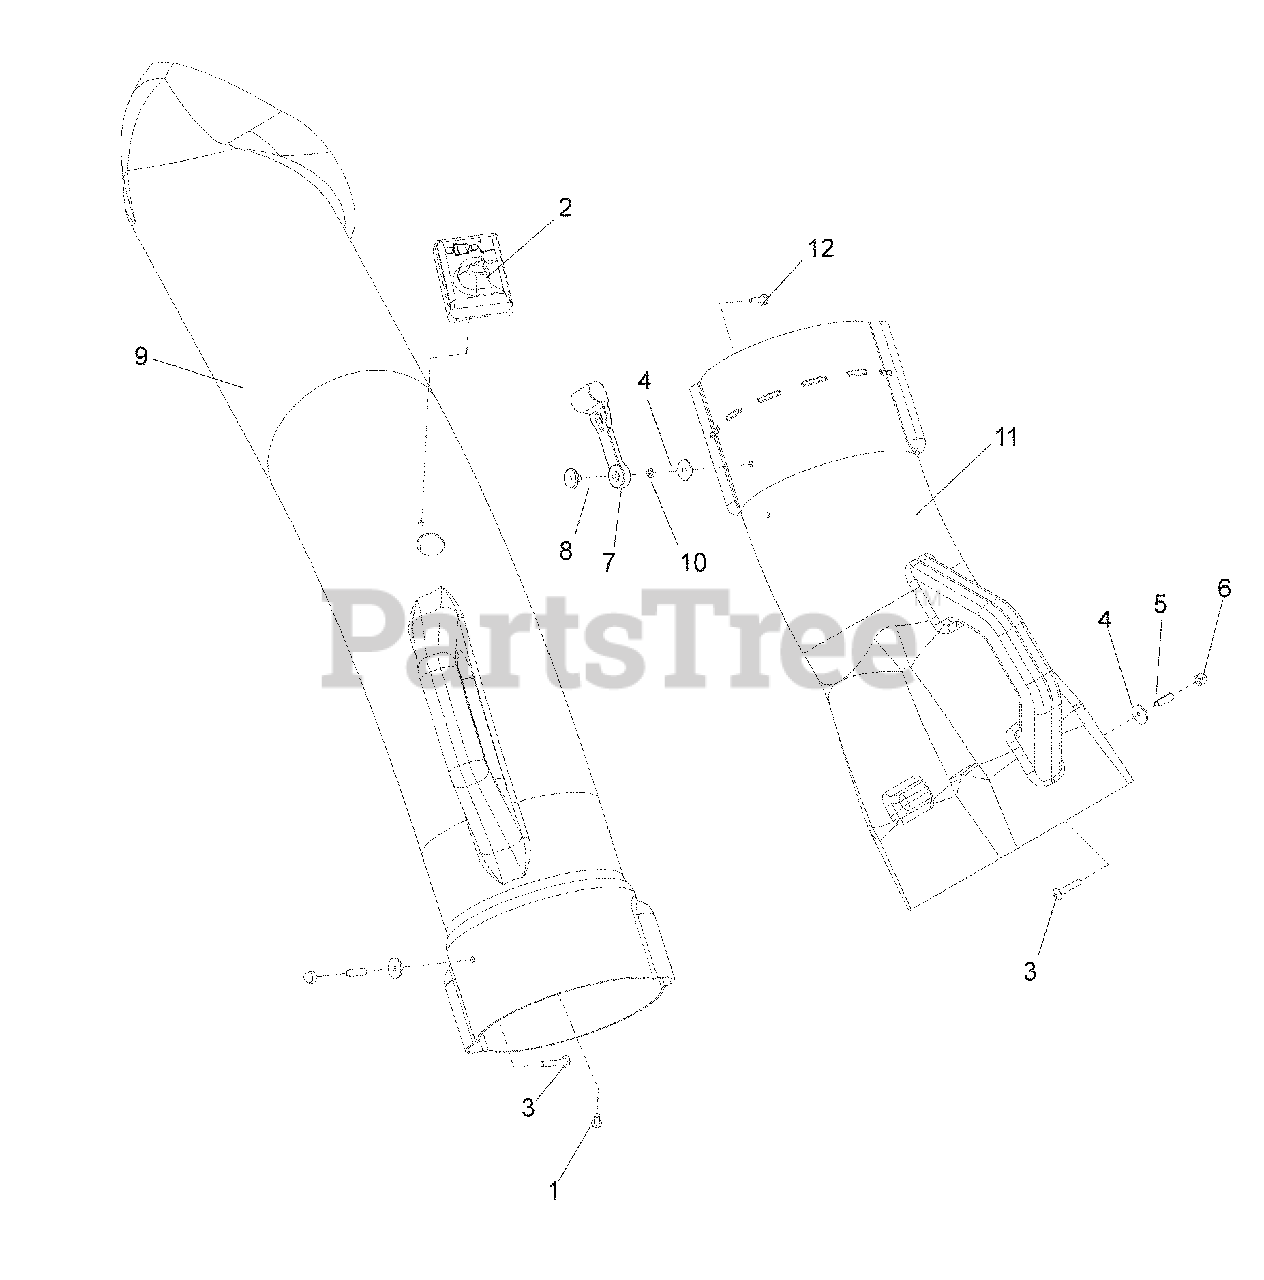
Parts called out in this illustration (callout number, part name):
1	SCREW, SPEC 10-14 x ½
2	INDICATOR, BAG DUMP
3	SCREW 10-24 x 11/8
4	WASHER 3/16 x ¾ x 16 GA
5	SPACER, SPLIT
6	NUT, ACORN 10-24
7	LATCH, HOOD
8	WELD NUT, PLATED
9	CHUTE, UPPER
10	WASHER 3/16 LOCK
11	CHUTE, MIDDLE
12	SCREW 10-24 x .625 MACH
